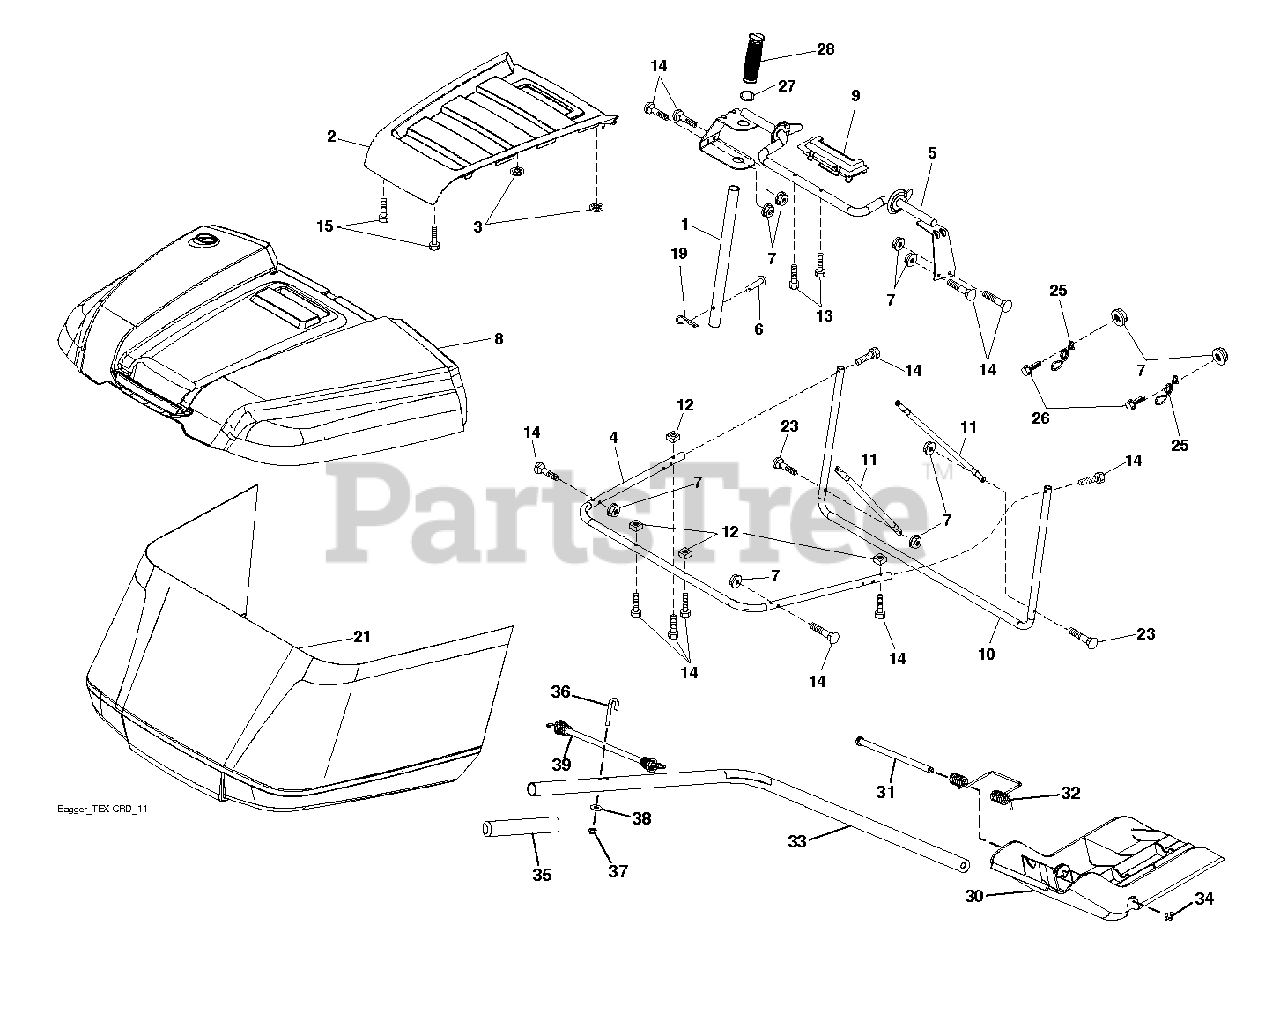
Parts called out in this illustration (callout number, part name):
1	TUBE.HANDLE.BAGGER.CRD/SRD.BLA
2	APPLIQUE.TOP.BAG.SRD.ORANGE
3	NUT.PUSH.156
4	SUBASM.TOP.TUBE.TEX.CRD
5	FRAME.ASM.TOP.BAGGER.SRD
6	RIVET,DRILLED
7	NUT T
8	BAGGER.TOP.SRD.APPLIQUE
9	INSERT.HANDLE.BAGGER.(2 2)
10	FRAME FRAME.FRONT.TEX.CRD
11	BRACE BRACE SIDE TUBE
12	NUT.SQUARE.1/4
13	SCREW.1/4X1.150.HXWSH
14	BOLT.SHOULDER.HX.WSH.1/4X1.150
15	SCREW,#8.FLAT.HEAD.DRILL.TIP
19	PIN.COTTER.5/16.BOW TI
21	BAG SUBASM. TEX CRD GEN 2 HUSQ
25	SPRING.LATCH.BAGGER.SRD
26	SCREW HEX CRT
27	RB GROMMET.RUBBER.SRD
28	GRIP.HANDLE.BLACK
30	PLUG PLUG
31	PIN PIN.HINGE
32	SPRING SPRING DOUBLE TORSION
33	SHAFT SHAFT TEX CRD MULCH PLU
34	E-RING.5/16"
35	GRIP GRIP MULCH PLUG HAND
37	Plug Support Bagger CRD
39	BUBGEE BUBGEE TEX CRD
